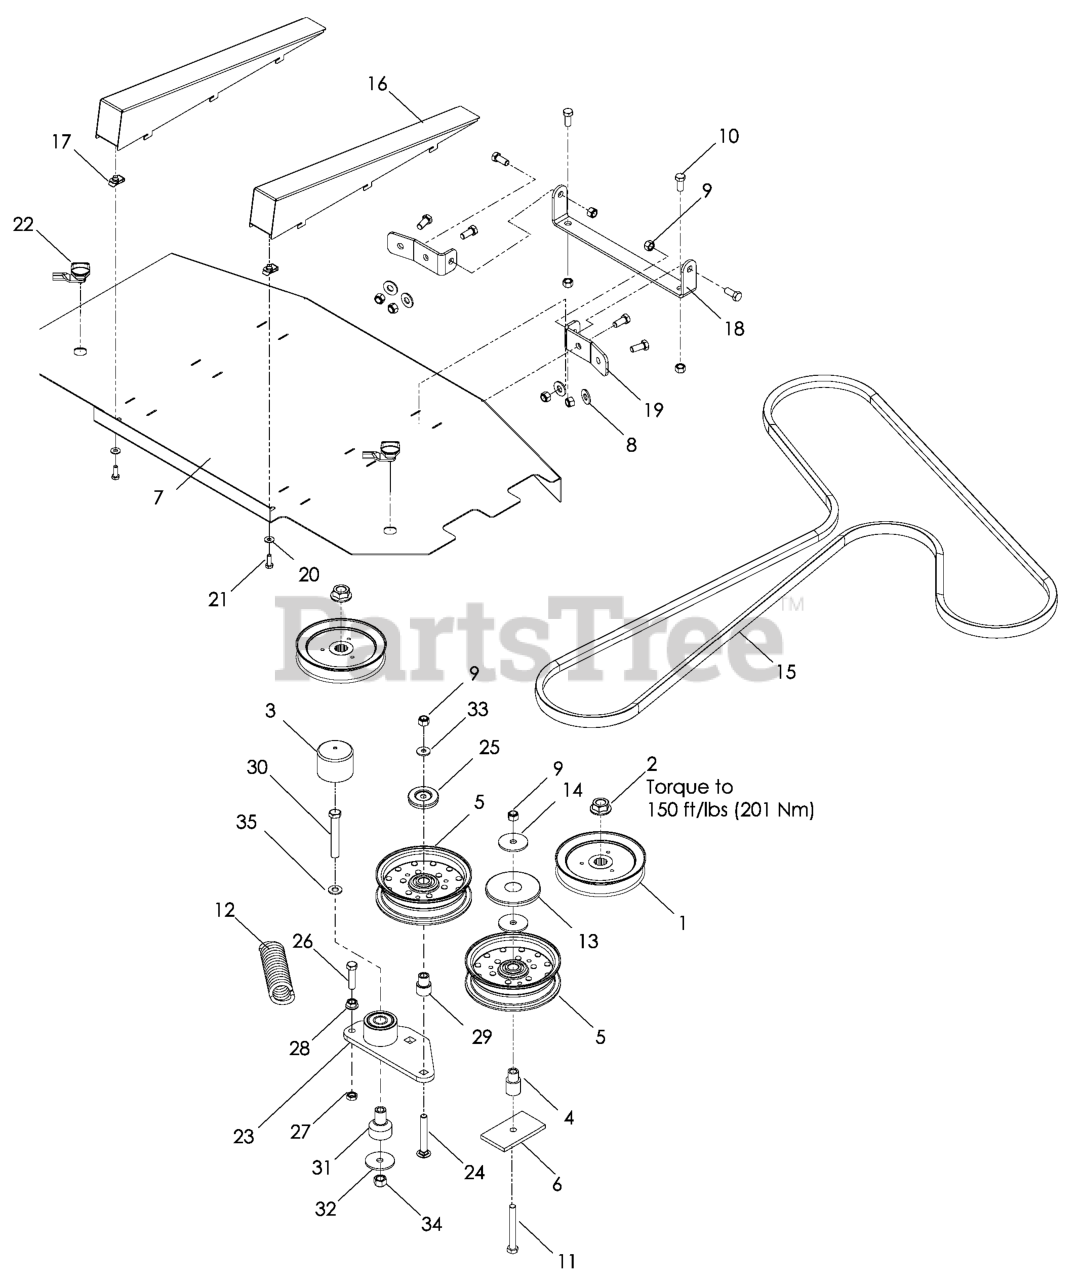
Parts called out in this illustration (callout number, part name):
1	PULLEY - 6.57
2	MOUNT-ROLLER, REAR RH 72"
3	CAP, VINYL
4	IDLER BUSHING
5	IDLER PULLEY
6	SUPPORT PLATE
7	COVER - BELT, 36 PAINTED
8	WASHER 3/8 FLAT
9	NUT 3/8-16 NYLOC
10	HCS 3/8-16 X 7/8 GR 5 ZD
11	HCS 3/8C X 3
13	TOP DUST CAP
14	WASHER, 3/8 SPEC
15	BELT - DECK 36 (103 L)
16	WEDGE - PAINTED
17	1/4C - U TYPE RETAINER
18	HINGE, BIN
19	BASE HINGE - PAINTED
20	WASHER 1/4 SAE
21	HCS 1/4C X 3/4 HCS
22	LATCH, SHORT WING
23	ARM-IDLER W/BRG
24	RHSNB 3/8-16 X 2.75
25	DUST SHIELD
26	HCS 3/8-16 X 1-1/2
27	NUT 3/8-16 HEX JAM
28	NUT 3/8C WHIZ
29	BUSHING, IDLER
30	HCS 1/2C X 3 1/4
31	PIVOT, BEARING
32	WASHER, SUPPORT
33	WASHER, 3/8 THICK
34	NUT 1/2-13 HEX NYLOC ZD
35	CONTACT BELLSPR 1/2
